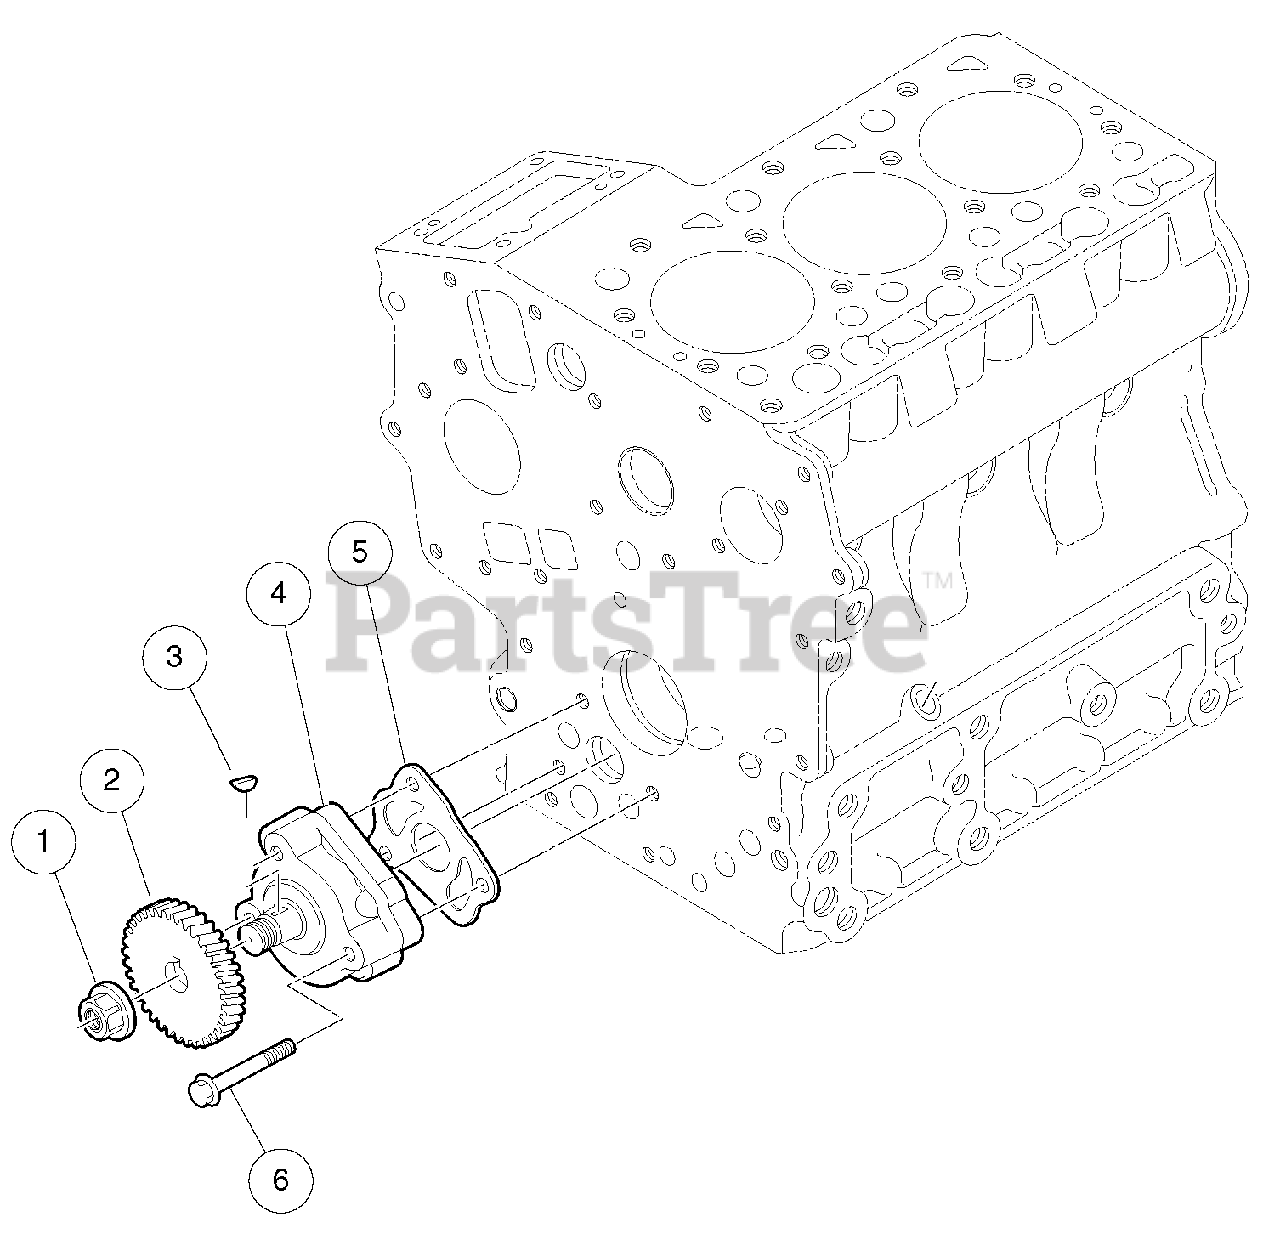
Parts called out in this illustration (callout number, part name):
1	Nut, Flange, D722 Oil Pump
2	Gear, Oil Pump Drive
3	Key, Feather, 8x4
4	Assy, Pump, Oil
5	Gasket, Oil Pump
6	Bolt, Oil Pump
